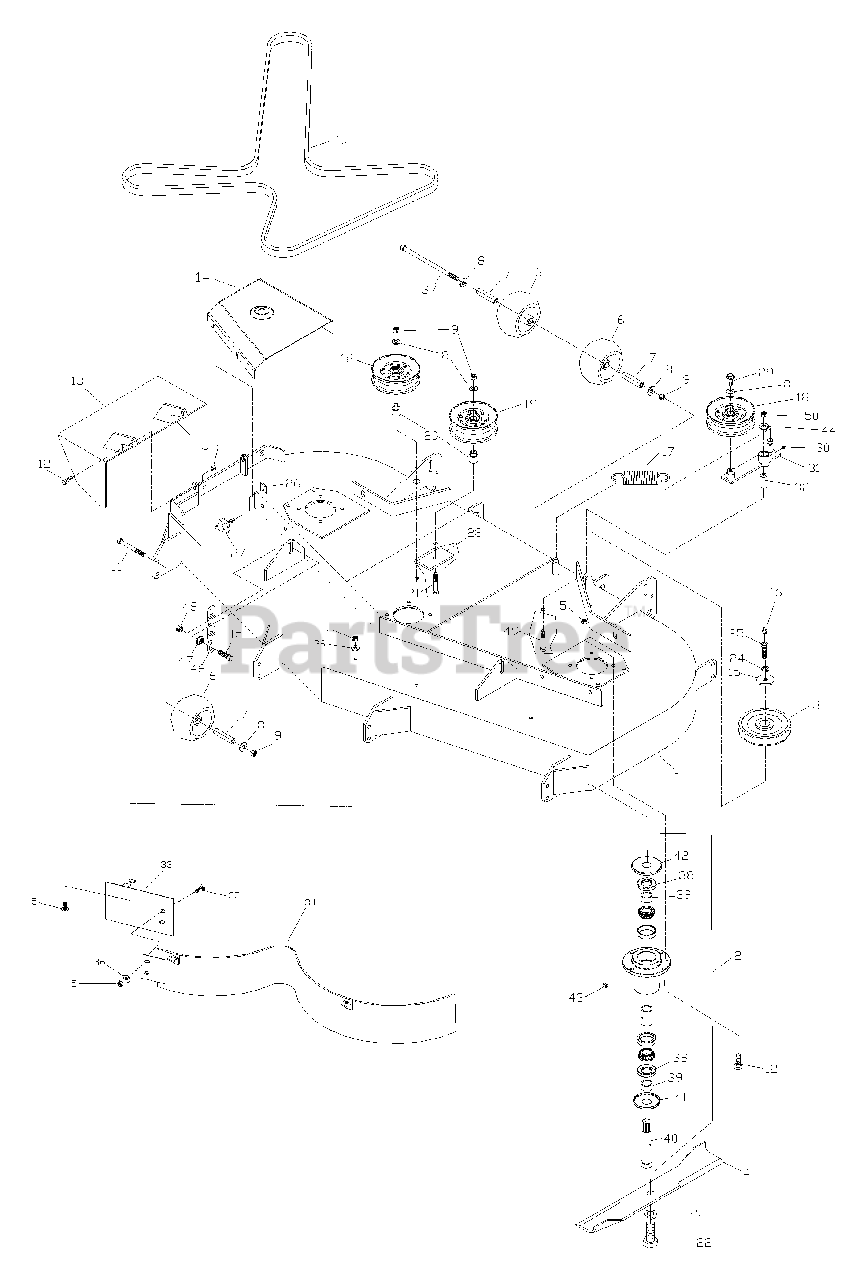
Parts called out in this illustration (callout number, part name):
1	DECK W/DECALS
2	CUTTER HOUSING ASM.
3	PULLEY
5	NUT 5/16 LOCK
8	3/8 FLAT WASHER
9	NUT 3/8 LOCK
11	HCS 3/8 X 3.5
12	HCS 5/16C X 1.00
13	DISCHARGE CHUTE
14	BELT SHIELD RT.
14	BELT SHIELD LT.
16	ZERK
18	PULLEY 1.31
19	PULLEY 1.62
20	IDLER BUSHING
21	HCS 3/8C X 2.5
22	HCS 5/8F X 2.0 GD. 8
23	5/8 SPRING WASHER
24	7/16 LOCK WASHER
25	HCS 7/16F X 1.5, SPECIAL
27	KNOB
28	PAD
29	HCS 3/8 X 1.0 SERR.
30	ZERK
32	PIVOT BUSHING
33	BAFFLE, CENTER
34	BAFFLE, MAIN
35	RHSNB 5/16 X 5/8
36	5/16 FLAT WASHER
37	HCS 3/8 X 6.0 GD. 8
38	SHAFT SEAL
40	MINI SPINDLE
41	DUST CAP, BOTTOM
42	DUST CAP, TOP
43	GREASE POPET
44	WASHER 1/2 FLAT
45	HCS 7/16 X 1.5
47	NUT 7/16 WHIZ
48	NUT 7/16 LOCK
49	HCS 1/2 X 3.25
50	NUT 1/2 NYLOC
